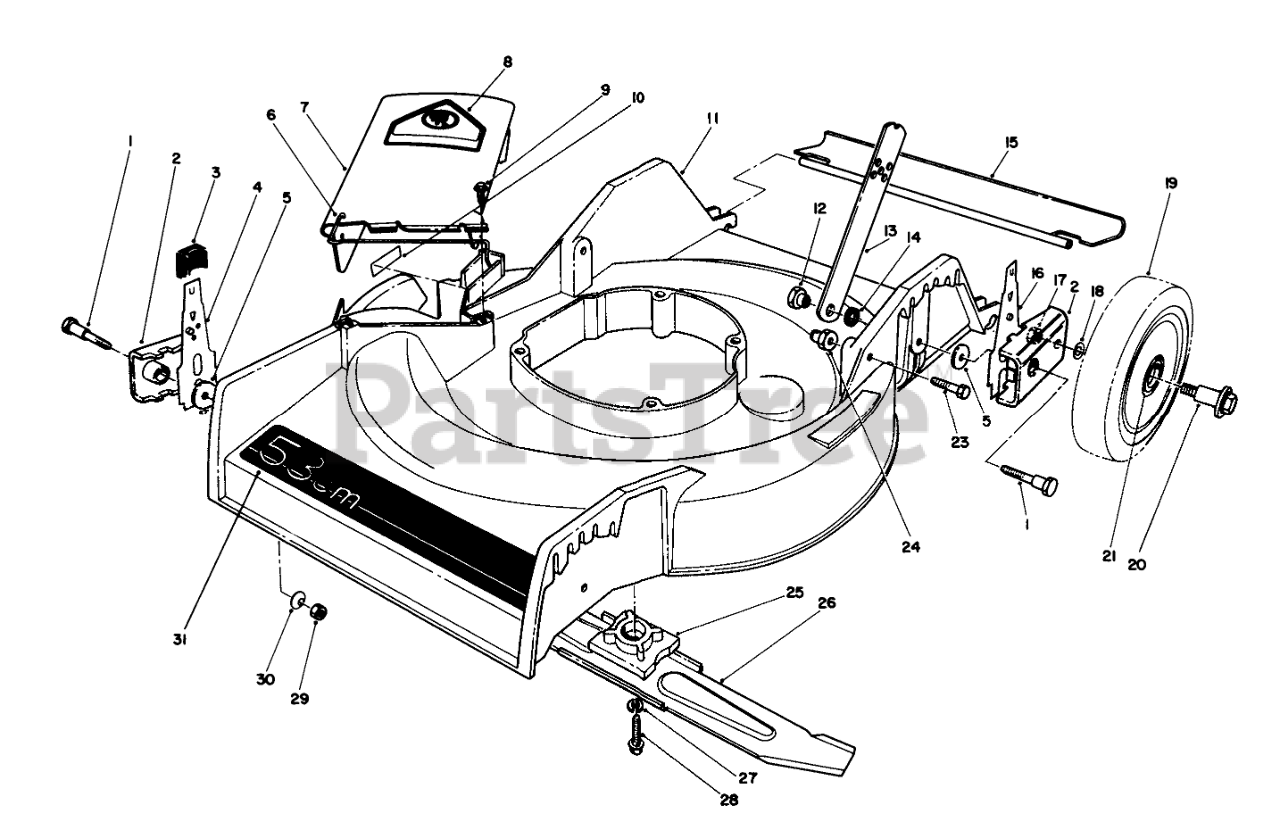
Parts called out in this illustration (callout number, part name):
1	PIVOT SCREW
2	HP PIVOT ARM ASM
3	KNOB-ARM
4	SPRING ARM ASSEMBLY
5	PIVOT WASHER
6	SPRING HINGE
7	Deflector Assembly (Incl. Ref. #6 & 8)
8	DECAL-DANGER
9	SCREW-HWH
10	DANGER DECAL
11	HOUSING W/ DECAL
12	HANDLE PIVOT NUT
13	HANDLE LATCH
14	SPACER
15	SHIELD - TRAILING
16	SPRING ARM ASSEMBLY
17	Nut
18	WASHER
19	Wheel & Tire Assembly (Incl. Ref. #21)
20	BOLT-WHEEL
21	BUSHING
23	SCREW-HH
24	HANDLE PIVOT NUT
25	BLADE RETAINER
26	Blade
27	WASHER-LOCK
28	SCREW-HH
29	NUT-LOCK, NI
30	WASHER-BELLEVILLE
31	DECAL - DECK, HP
